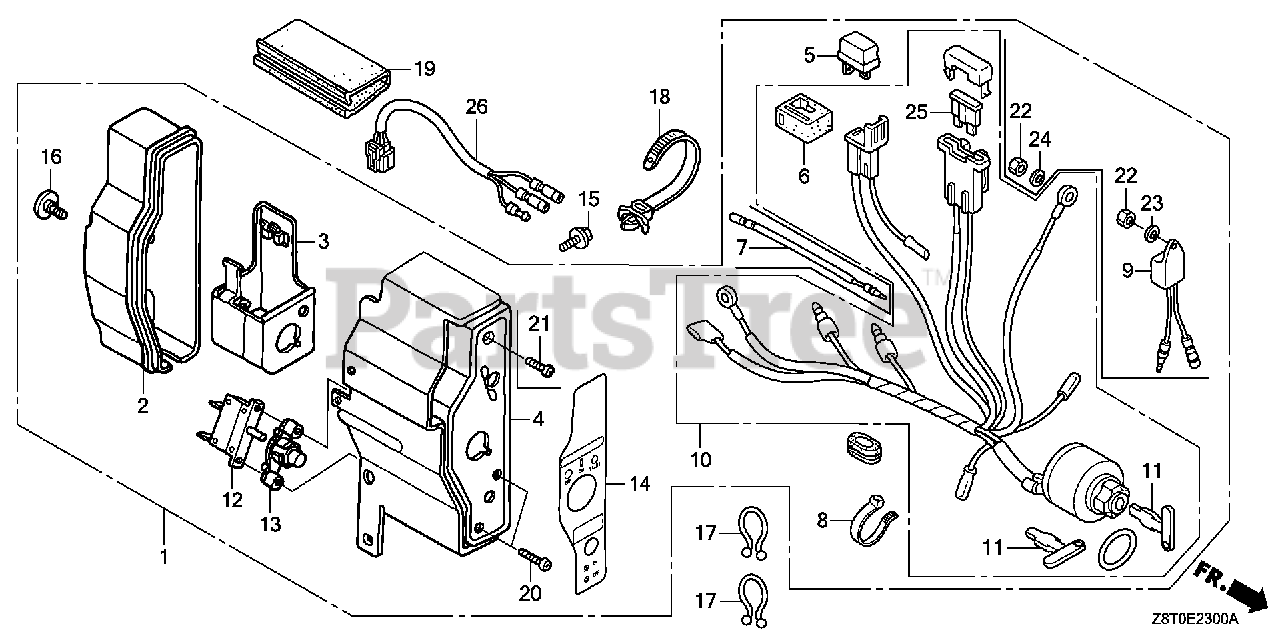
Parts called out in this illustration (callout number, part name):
1	BOX ASSY., CONTROL (3A) *NH1* (EXP-ALERT) (BLACK)
1	BOX ASSY., CONTROL (3A) *R280* (EXP-ALERT) (POWER RED)
2	CASE, CONTROL
3	BRACKET, CASE MOUNTING
4	PANEL, CONTROL *NH1* (BLACK)
4	PANEL, CONTROL *R280* (POWER RED)
5	RECTIFIER ASSY., SILICON (SHINDENGEN)
6	SUSPENSION, CONNECTOR
7	SUB-WIRE HARNESS
9	ALERT UNIT, OIL
10	SWITCH ASSY., COMBINATION (3A-CHARGE)
11	KEY (HONDALOCK)
12	PROTECTOR, CIRCUIT (3.5A)
13	LENS ASSY., PROTECTOR
14	MARK, CONTROL BOX (EXTERNAL)
15	BOLT, FLANGE (6X12) (CT200)
16	SCREW, SPECIAL (6X12)
17	CLIP, PURSE LOCK
18	STRAP, CABLE (118MM) (BLACK)
19	TUBE, FASTENER (30MM)
20	SCREW, PAN (3X12)
21	SCREW, PAN (4X12)
22	NUT, HEX. (4MM) (SOURCE: VINTAGE PARTS INC.)
23	WASHER, PLAIN (4MM)
24	WASHER, SPRING (4MM)
25	FUSE, BLADE (15A)
